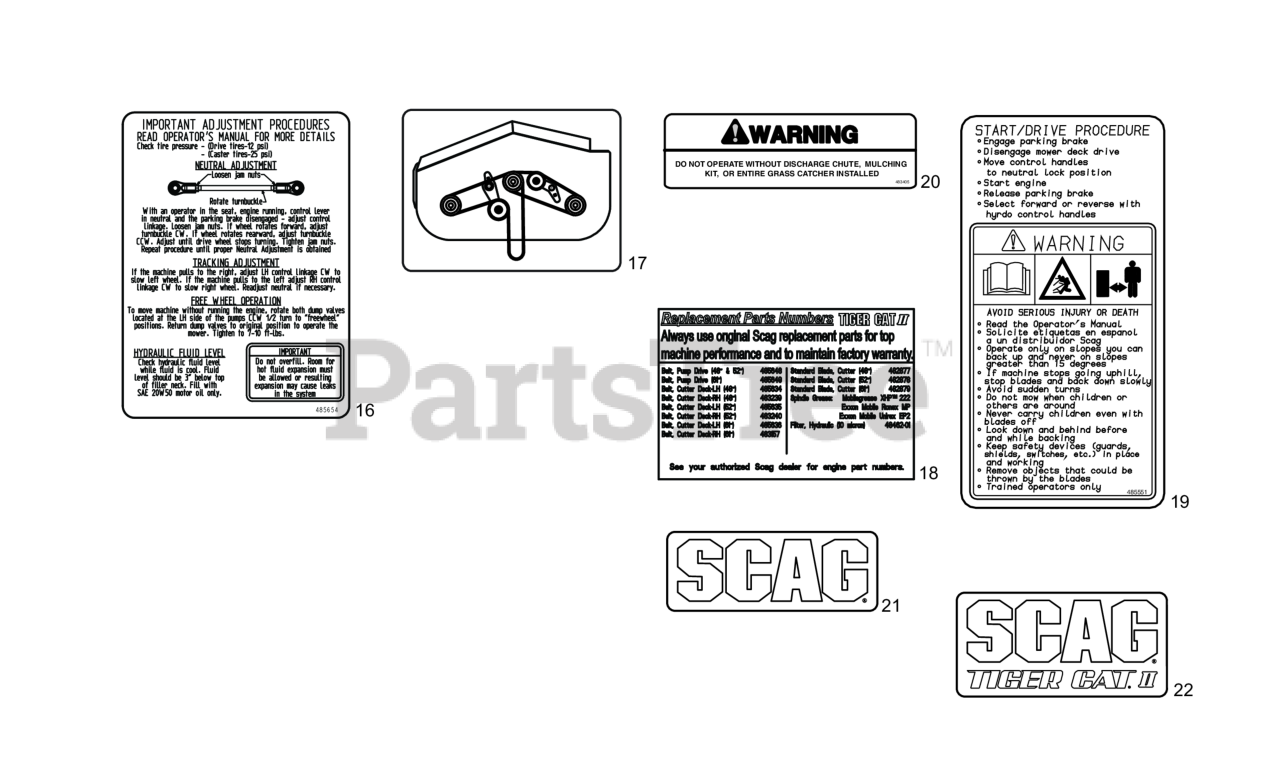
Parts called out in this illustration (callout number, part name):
16	Decal, Seat Support
17	Decal, Cutter Deck Belt Routing
18	Decal, STCII Replacement Parts
19	Decal, Start/Drive
20	Decal, Warning-Discharge
21	Decal, Scag
22	Decal, Scag Tiger Cat II
